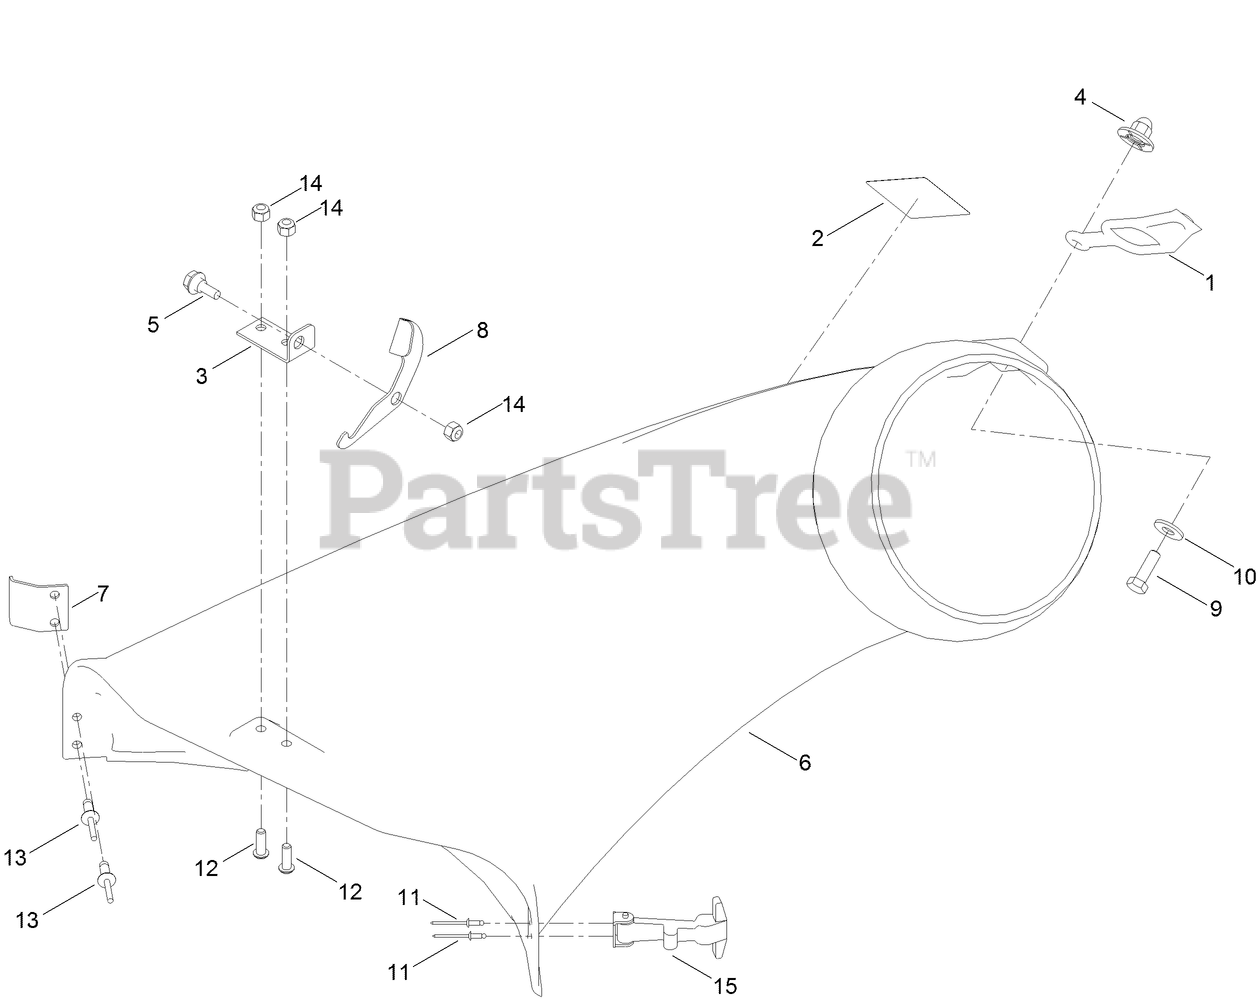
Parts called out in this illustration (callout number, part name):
1	RETAINER-DUCT
2	DECAL-DANGER
3	PLATE-PIVOT
4	NUT-IMPELLER
5	SCREW-SHOULDER,HWH
6	42 INCH BAGGER BOOT
7	BRACKET-ELBOW
9	SCREW-HH
10	WASHER-FLAT
11	RIVET-POP
12	SCREW-HSBH
13	RIVET-BLIND
14	NUT-LOCK, NI
15	HANDLE ASM
